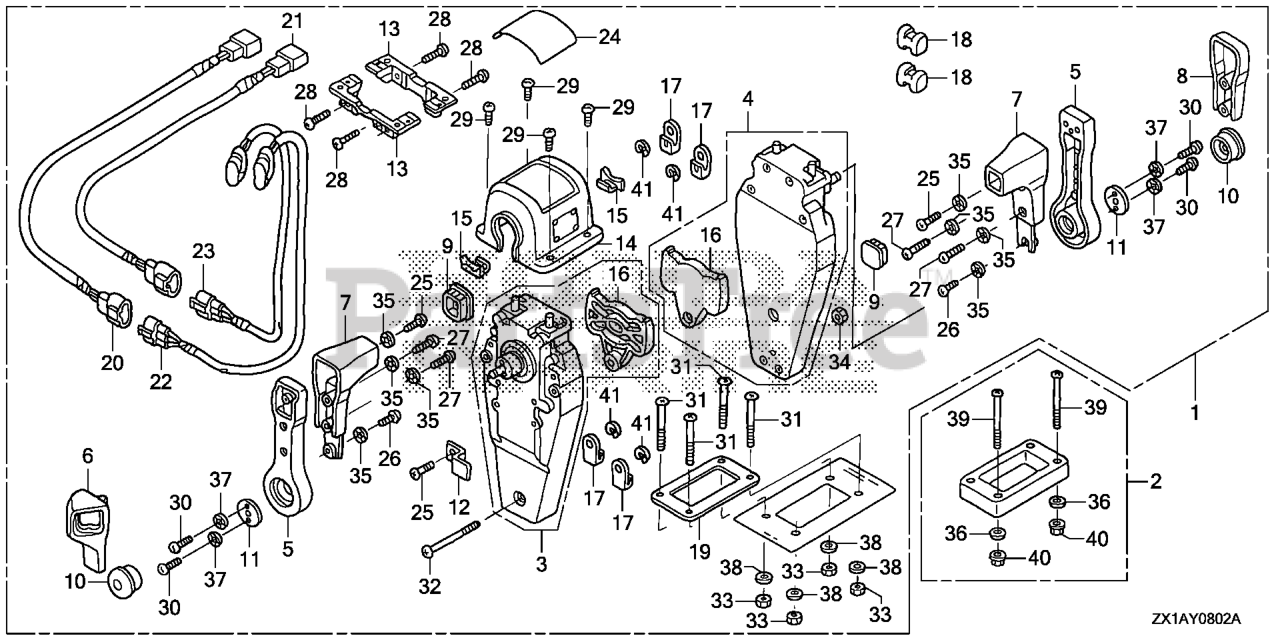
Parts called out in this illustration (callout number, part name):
1	BOX KIT, R. REMOTE CONTROL (TOP MOUNT DUAL)
1	BOX KIT
2	SPACER KIT, REMOTE CONTROL BOX (TOP MOUNT DUAL)
3	HOUSING ASSY., L. (INNER) (TOP MOUNT)
4	HOUSING ASSY., R. (INNER) (TOP MOUNT)
5	HANDLE, REMOTE CONTROL
6	COVER, L. GRIP
7	GRIP, REMOTE CONTROL HANDLE
8	COVER, DUAL GRIP
9	CAP, GRIP
10	BUTTON, THROTTLE
11	PLATE, HANDLE
12	PLATE, CABLE CLAMP
13	BRACKET, REMOTE CONTROL HOUSING
14	HOUSING, DUAL REMOTE CONTROL BOX
15	HOUSING, LEAD
16	PLATE, DWELL
17	TERMINAL, CABLE
18	SPACER, CABLE CLAMP
19	GASKET, DUAL
20	SUB-HARNESS ASSY., POWER TRIM-TILT (A)
21	SUB-HARNESS ASSY., POWER TRIM-TILT (B)
22	SWITCH ASSY., POWER TRIM-TILT (A)
23	SWITCH ASSY., POWER TRIM-TILT
24	MARK, REMOTE CONTROL (DUAL)
25	SCREW, PAN (5X16)
26	SCREW, PAN (5X10)
27	SCREW, PAN (5X20)
28	SCREW, PAN (5X18)
29	SCREW, PAN (4X10)
30	SCREW, PAN (6X18)
31	SCREW, PAN (5X40)
32	SCREW, PAN (5X55)
33	NUT, HEX. (5MM)
34	NUT, HEX. (5MM)
35	WASHER, LOCK (5MM)
36	WASHER, PLAIN (5MM)
37	WASHER, LOCK (6MM)
38	WASHER, PLAIN (5MM)
39	SCREW, PAN (5X65)
40	NUT, HEX. (5MM)
41	E-RING (6MM)
